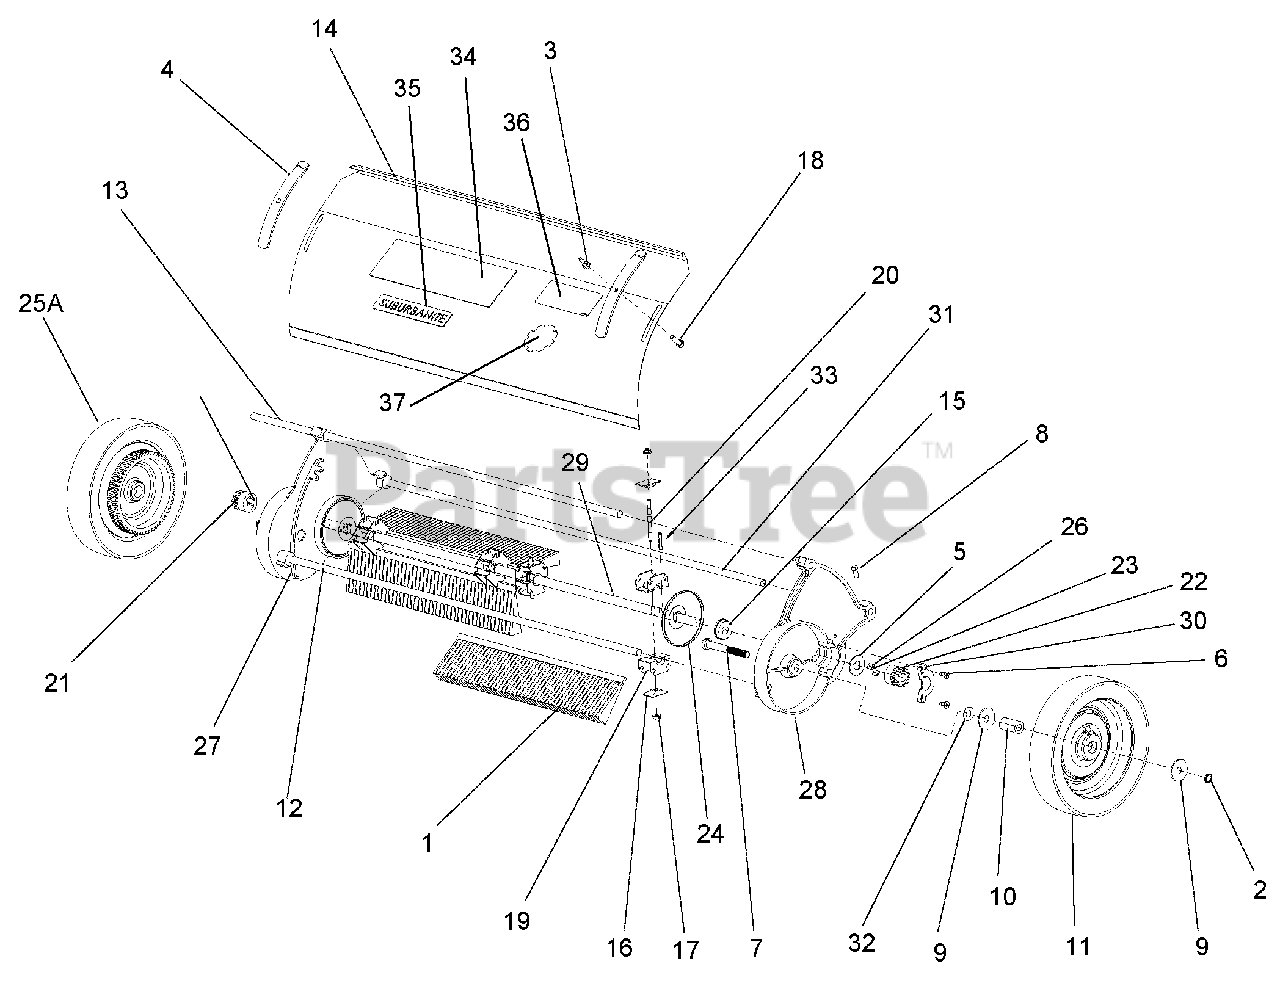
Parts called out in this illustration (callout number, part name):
1	Brush Assembly
1A	Brush Kit (includes mounting hardware)
2	Nut, Jam, Nyloc .50-20 GR2
3	Nut, Wing .312-18
4	Clamp, Hood
5	Washer, .656 x 1.50 x .06 Flat
6	Screw, Flathead, .25-20 x .63
7	Bolt, Axle
8	SWP, Square Head Set Screw
9	Washer, 5.16 x 1.625 x .075 Flat
11	Wheel Hub
12	Tie Rod, Zinc Plated
13	Tie Rod
14	SWP, Hood with Decals, SU, Gravely
15	Bearing, .625 x .150 Flange Radial
16	Clamp, Brush Strip
17	Nut, Locking, Flange .25-20
18	Bolt, 5/16-18 x 1 Hex 5
20	Stud, Plated Zinc
21	Pinion, Right
22	Pinion, Left
22A	Pinion Kit (includes items 21, 22, 23 & 26)
23	Dowel Pin, .1875" OD x .4375"
24	Dust Cover, Zinc Plated
25	Tire Only
25A	Tire Assembly (includes items 11 & 25)
26	Pawl Spring
27	Side Plate, Right
28	Side Plate, Left
29	Shaft, Reel, Plated
30	Casting, Cover Pinion
31	Adjust Tube, 1/2 x .065 Zinc Plated
32	Washer, .656 x 1.50 x .06 Fiber
33	Pin, Roll 3/16 x 1.0
34	Decal,Gravely Logo
35	Decal, Suburbanite
36	Decal, Danger Read Manual
37	Decal, Gravely Heritage-Small
